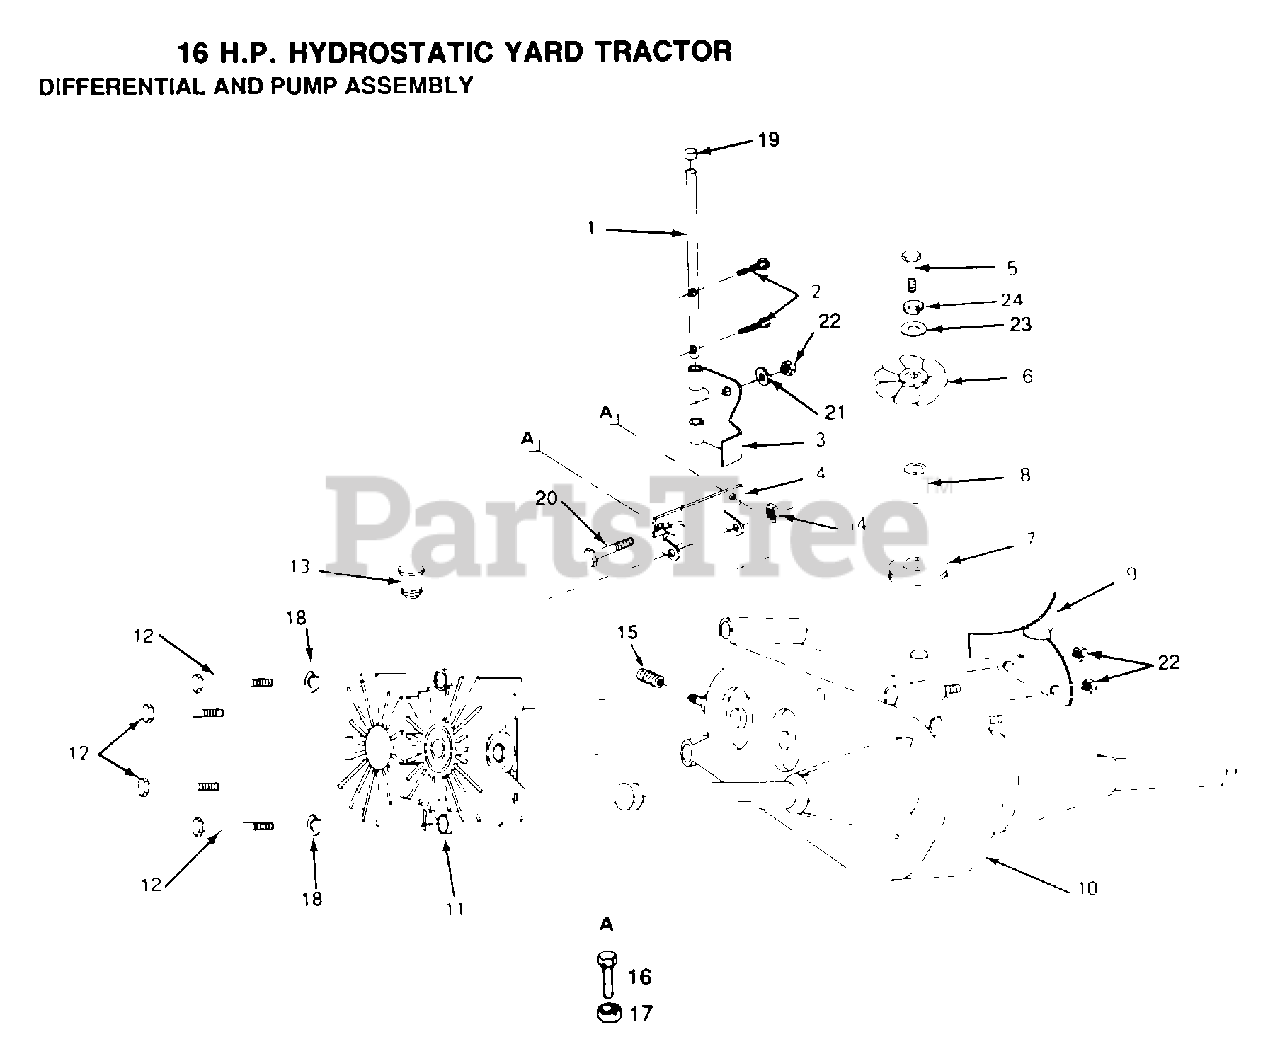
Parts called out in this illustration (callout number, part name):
4	BRACKET
6	FAN
7	PULLEY TRANSAXLE
8	STANDOFF
9	GUARD ASSY
12	BOLT
13	PUMP.2003081.
15	SPRING
16	BOLT, 3/8 - 16 X 3/4
18	LOCKWASHER
19	PLUNGER CAP T
20	BOLT T
21	WASHER T
23	WASHER
24	LOCKWASHER
